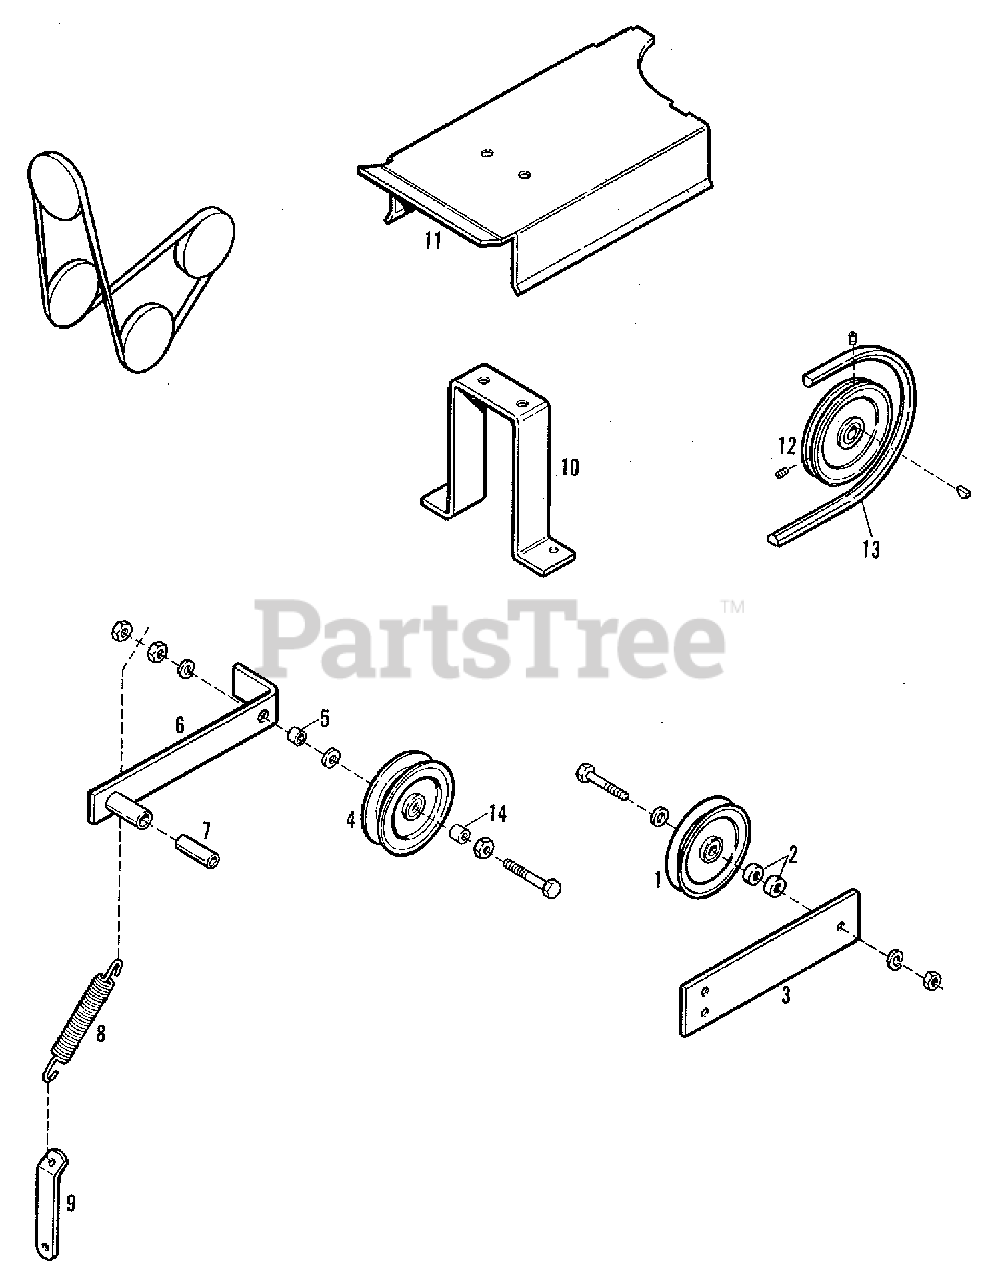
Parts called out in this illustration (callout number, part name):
1	PULLEY ASSEMBLY
1	CAPSCREW, 3/8NC x 2
1	WASHER, Plain, 3/8 x 7/8 x 16 Ga.
1	LOCKWASHER, 3/8
3	CAPSCREW, 3/8NC x 1-1/4
3	LOCKWASHER, 3/8
4	CAPSCREW, 3/8NC x 2-1/4
4	WASHER, Plain, 13/32 x 7/8 x 14 Ga
4	LOCKWASHER, 3/8
4	NUT, Jam, 3/8NC
6	ARM ASSEMBLY, Idler
6	CAPSCREW, 3/8NC x 2-1/4
6	WASHER, Plain, 13/32 x 7/8 x 14 Ga
6	LOCKWASHER, 3/8
9	BRACKET, Spring
9	CAPSCREW, 3/8NC x 1-1/4
9	LOCKWASHER, 3/8
10	BRACKET, Cover
10	SCREW, Taptite, 1/4NC x 3/4
11	CAPSCREW, 5/16NC x 3/4
11	WASHER, Plain, 3/8 x 7/8 x 16 Ga.
11	LOCKWASHER, 5/16
11	NUT, 5/16NC
12	SETSCREW, 5/16NC x 1/2
12	KEY, Hi-Pro, 3/16 x 3/4
